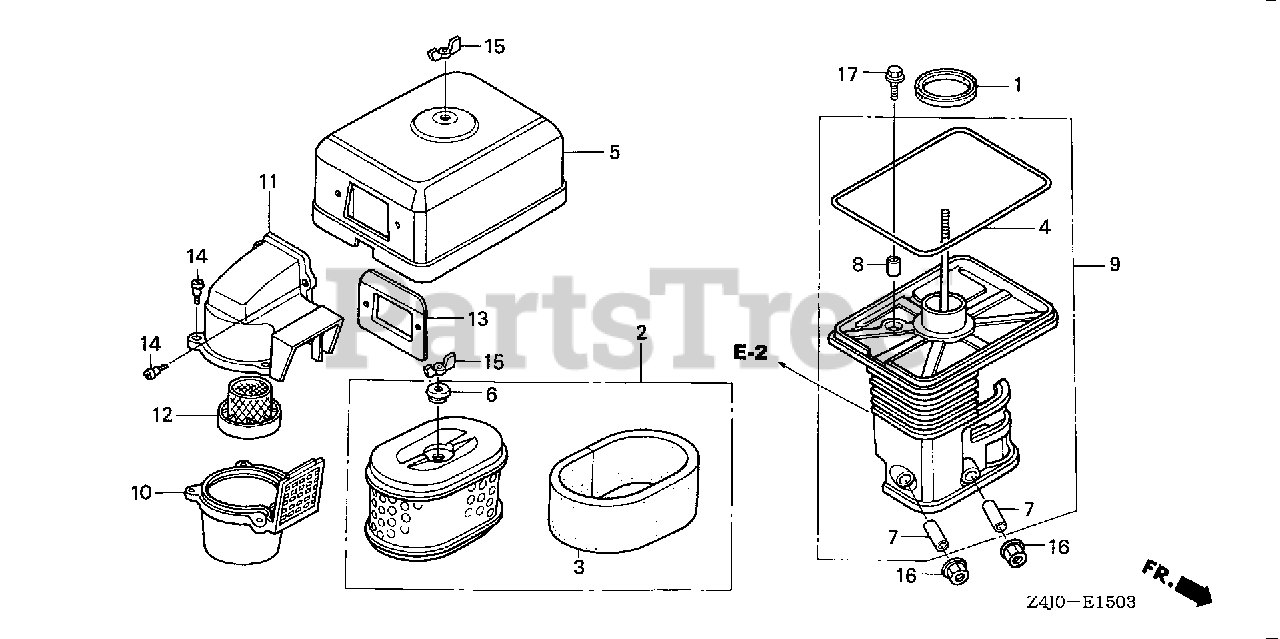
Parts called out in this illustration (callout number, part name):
1	GASKET, ELBOW
2	ELEMENT, AIR CLEANER (DUAL)
3	FILTER (OUTER)
4	GASKET, AIR CLEANER COVER
5	COVER, AIR CLEANER (CYCLONE)
6	GROMMET, AIR CLEANER
7	COLLAR, AIR CLEANER
8	COLLAR B, AIR CLEANER
9	ELBOW, AIR CLEANER
10	CASE, PRE AIR CLEANER
11	CAP, PRE AIR CLEANER
12	GUIDE, PRE AIR CLEANER
13	PLATE, PRE AIR CLEANER
14	BOLT, SPLASH GUARD
15	NUT, TOOL BOX SETTING
16	NUT, FLANGE (6MM)
17	BOLT, FLANGE (6X20)
